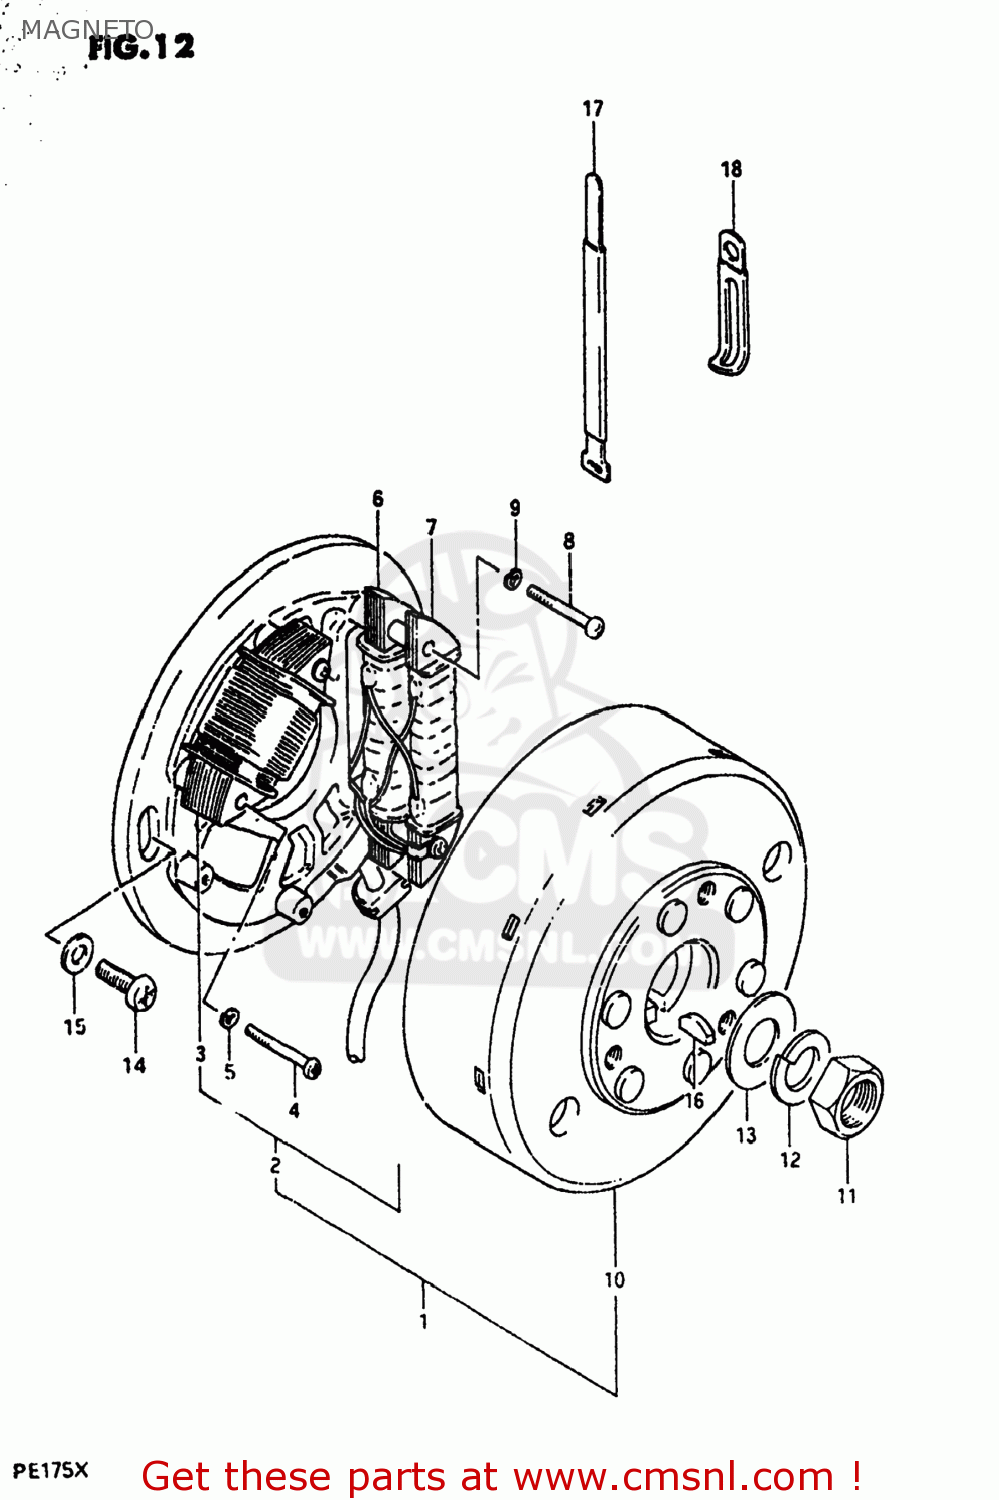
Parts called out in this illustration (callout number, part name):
1	MAGNETO ASSEMBLY
2	STATOR ASSEMBLY
3	COIL,LIGHTING
4	SCREW (4X30)
5	LOCK WASHER
6	COIL
7	COIL,PRIMARY
8	SCREW (4X30)
9	LOCK WASHER
10	ROTOR ASSEMBLY
11	NUT (10MM)
12	LOCK WASHER
13	WASHER
14	SCREW
15	WASHER
16	KEY 4MM
17	CLAMP
18	CLAMP
